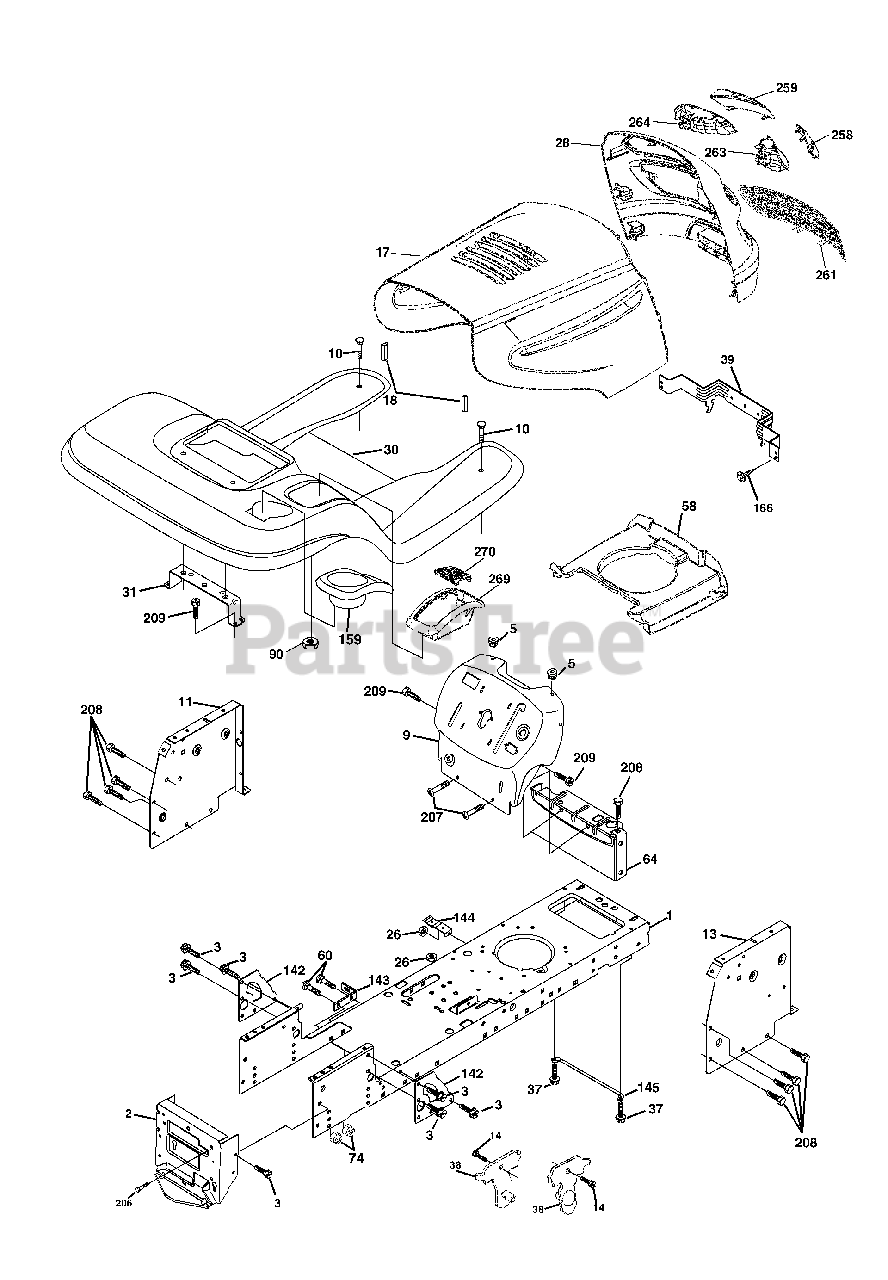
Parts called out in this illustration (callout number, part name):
1	Chassis
2	Drawbar
3	Screw 3/8-16 X .75
5	Bumper Hood/Dash
9	Dash P/L
10	Bolt Carriage 3/8-16 x 1
11	Panel Dash Lh
13	Panel Dash Rh
14	Screw Thdrol 3/8-16 x 1/2
17	Hood
18	Bumper Hood
26	Nut Lock Hex W/Ins 3/8-16 Unc
28	Grille/Lens Asm
30	Fender Footrest
31	Bracket Fender
37	Screw Thdrol 6/16-18 x 1/2 TYT
38	Bracket Asm Pivot Mower Rear
39	Bracket Pivot
58	Duct Air
60	Bolt 3/8-16 x 3/4
64	Dash Lower STLT
74	Nut Crownlock 3/8-16
90	Nut Self-Thd Wsh-Hd 1/4
142	Plate Reinforcement STLT
143	Bracket Swaybar Chassis
144	Bracket Footrest Step-Thru
145	Rod Pivot Chassis/Hood
159	Cupholder
166	Screw Hwhd Hi-Lo #13-16 x 3/4
206	Bolt Shoulder 5/16-18
207	Screw Thdrol 5/16-18 x 1/2
208	Screw Thdrol 3/8-16 x 1/2
209	Screw Hexwsh Thdr 3/8-16 x 3/4
258	Lens Grille Pro RH
259	Lens Grille Pro LH
263	Bezel Grille LH
264	Bezel Grille RH
269	Toolbox Asm.
270	Toolbox Lid
